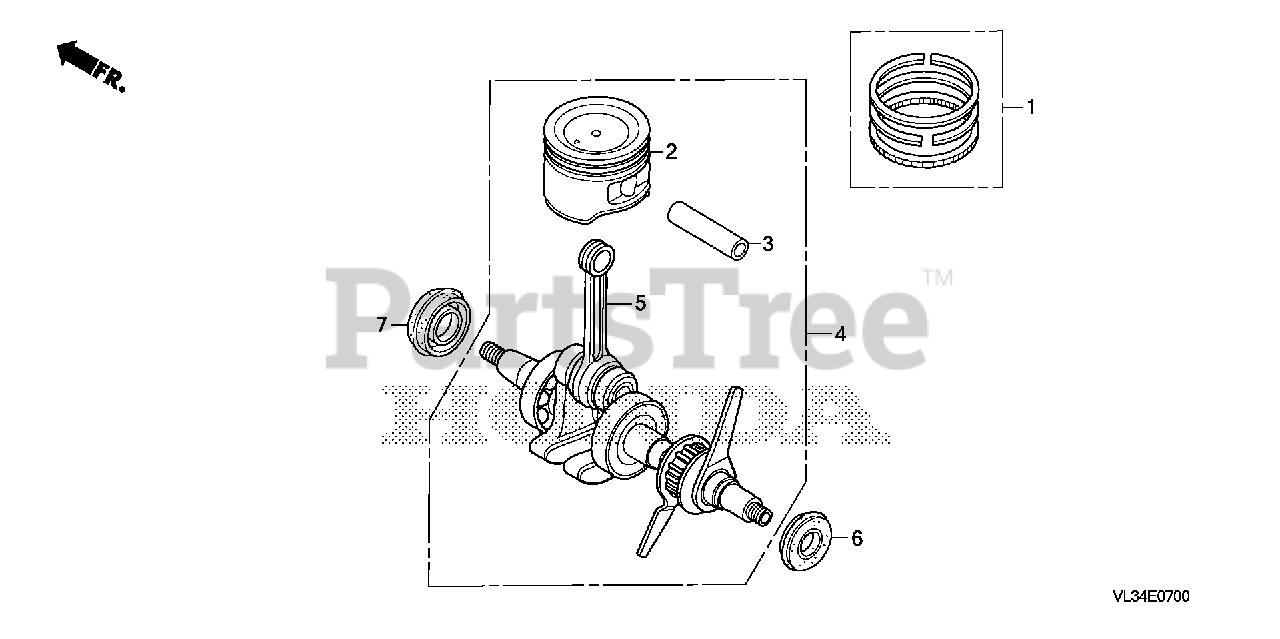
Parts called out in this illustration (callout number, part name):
1	RING SET, PISTON (RIKEN)
1	RING SET, PISTON (TPR)
2	PISTON
3	PIN, PISTON
4	CRANKSHAFT
5	CRANKSHAFT
6	OIL SEAL (10X20X5)
7	OIL SEAL (15X25X6)
